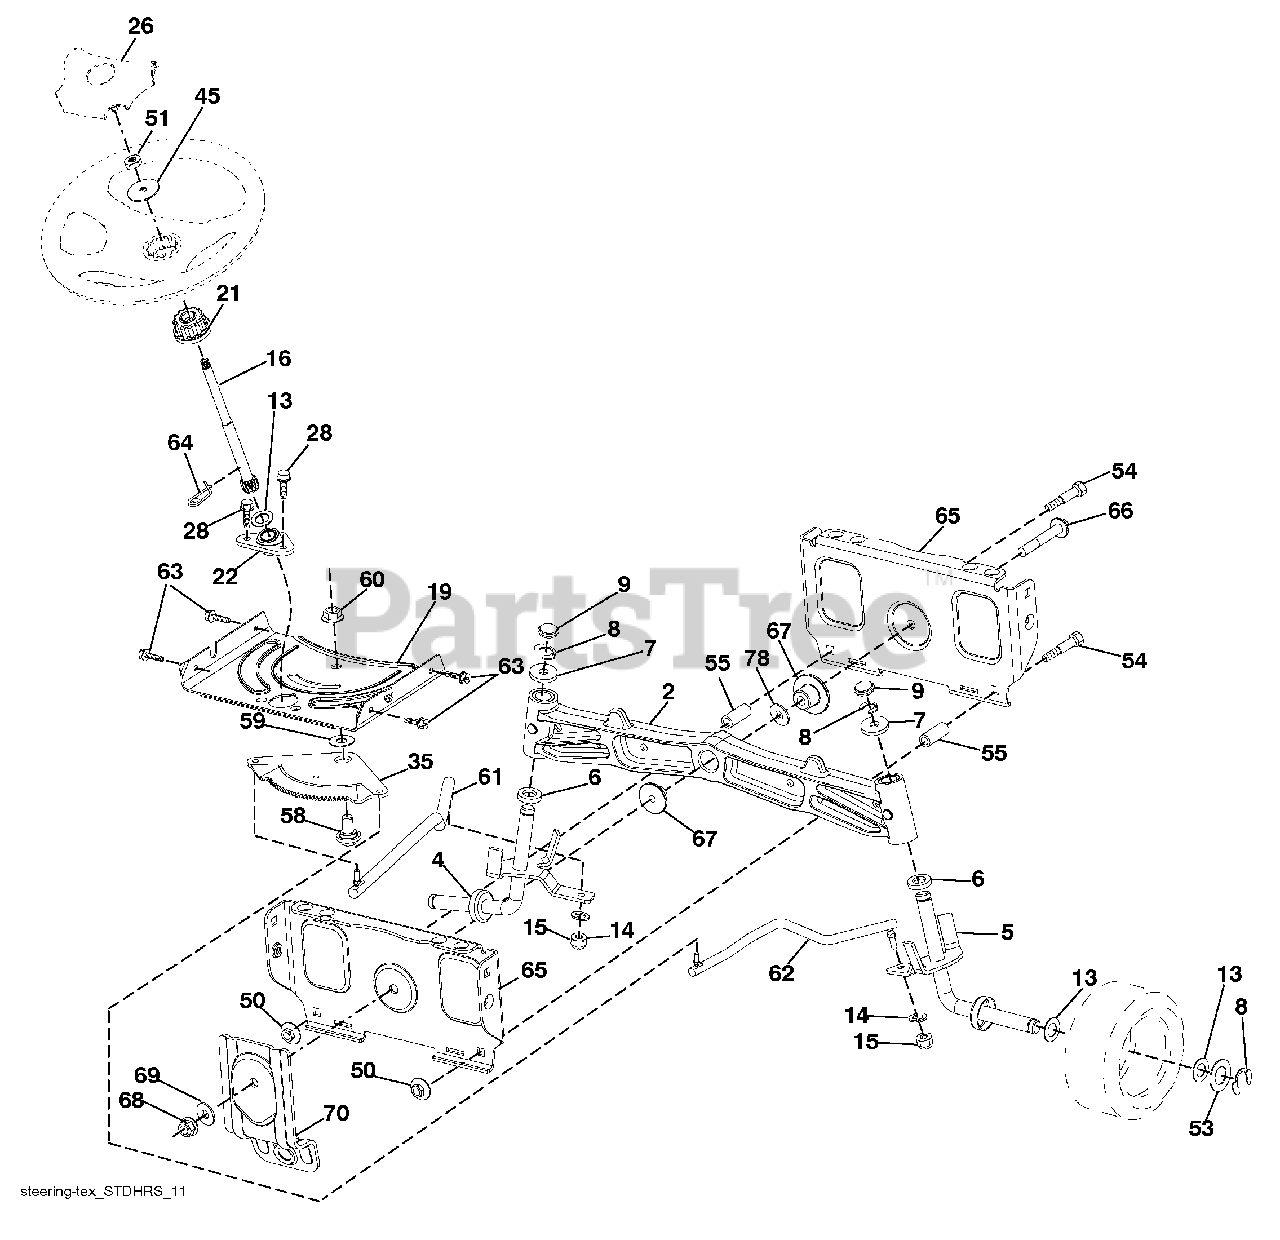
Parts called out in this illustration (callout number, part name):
1	Wheel, Steering
2	Axle Asm., Front
4	Spindle Asm. LH
5	Spindle Asm. RH
6	Bearing, Race Thrust Harden
7	Washer 25/32 x 1-5/8 x 16 Ga.
8	Ring, Clip #T5304-75
9	Cap, Spindle
13	Washer 25/32 x 1-1/4 x 16 Ga.
14	Washer, Lock Hvy Hlcl Spr 3/8
15	Nut, Crown Lock 3/8-24 unf
16	Shaft Steering
19	Plate Steering
21	Adapter, Wheel Steering
22	Steering Support Lower
26	Insert, Wheel Steering
28	Screw 3/8-16 x 3/4
35	Gear, Sector Plate
45	Washer 9/16 x 2-3/8 x 12 Ga.
50	Nut Lock Flange 3/8-16 unc
51	Nut Hex Jam Toplock 1/2-20 unf
53	Washer Hardened .793 x 1.637 x .060
54	Bolt Hex 3/8-16 unc x 2-1/4
55	Bolt Hex 3/8-16 unc x 2-1/4
58	Bolt Shoulder Sector Pivot CFM
59	Washer Thrust Sector Steering
60	Nut Flange Lock 5/8-11
61	Draglink, LH
62	Draglink, RH
63	Screw 5/16-18 x 3/4
64	Retainer Clip Spring Steering
65	Brace Axle Front
66	Bolt Hex Fghd 7/16-14 x 3 Serr
67	Bushing PM Front Axle
68	Nut Lock Flange 7/16-14 Gr. 5
69	Washer 1.5 x .505 x .118
70	Bracket Deck Susp. Front
78	Washer Thrust
